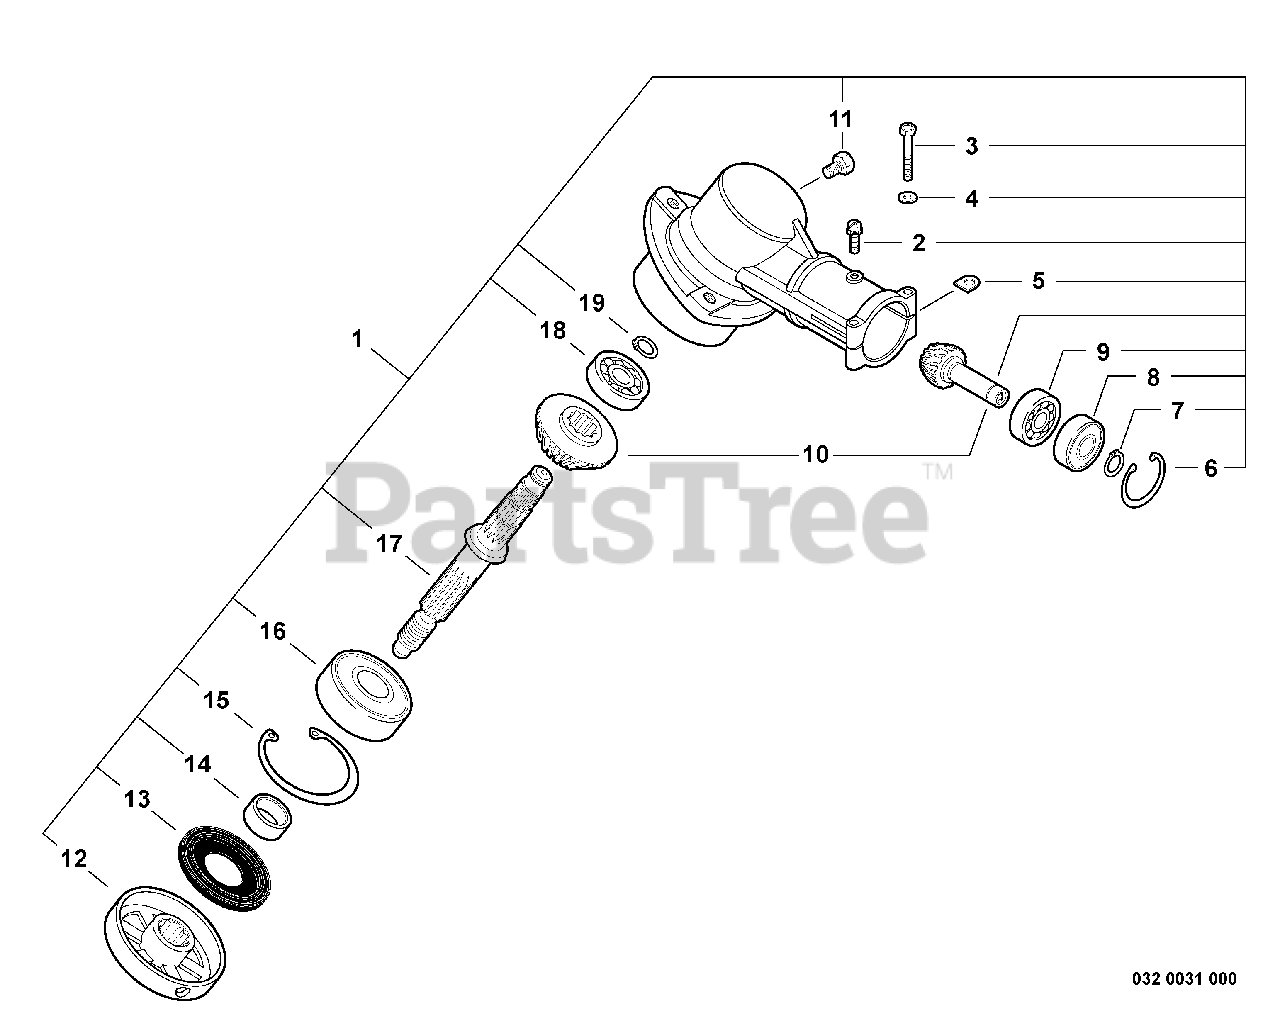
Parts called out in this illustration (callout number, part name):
1	GEAR CASE ASSY
2	SCREW - 5X10
3	BOLT - 5X35
4	WASHER - 5
6	RING, RETAINING - 22
7	RING, RETAINING - 10
8	BEARING, BALL - 6900Z
9	BEARING, BALL - 6900
10	GEAR SET - BEVEL
11	BOLT - 8X8
12	ADAPTOR, BLADE - UPPER
13	SEAL, OIL
15	RING, RETAINING - 32
16	BEARING, BALL - 6201
17	GEAR - SHAFT
18	BEARING, BALL - 609
19	RING, RETAINING - 10
